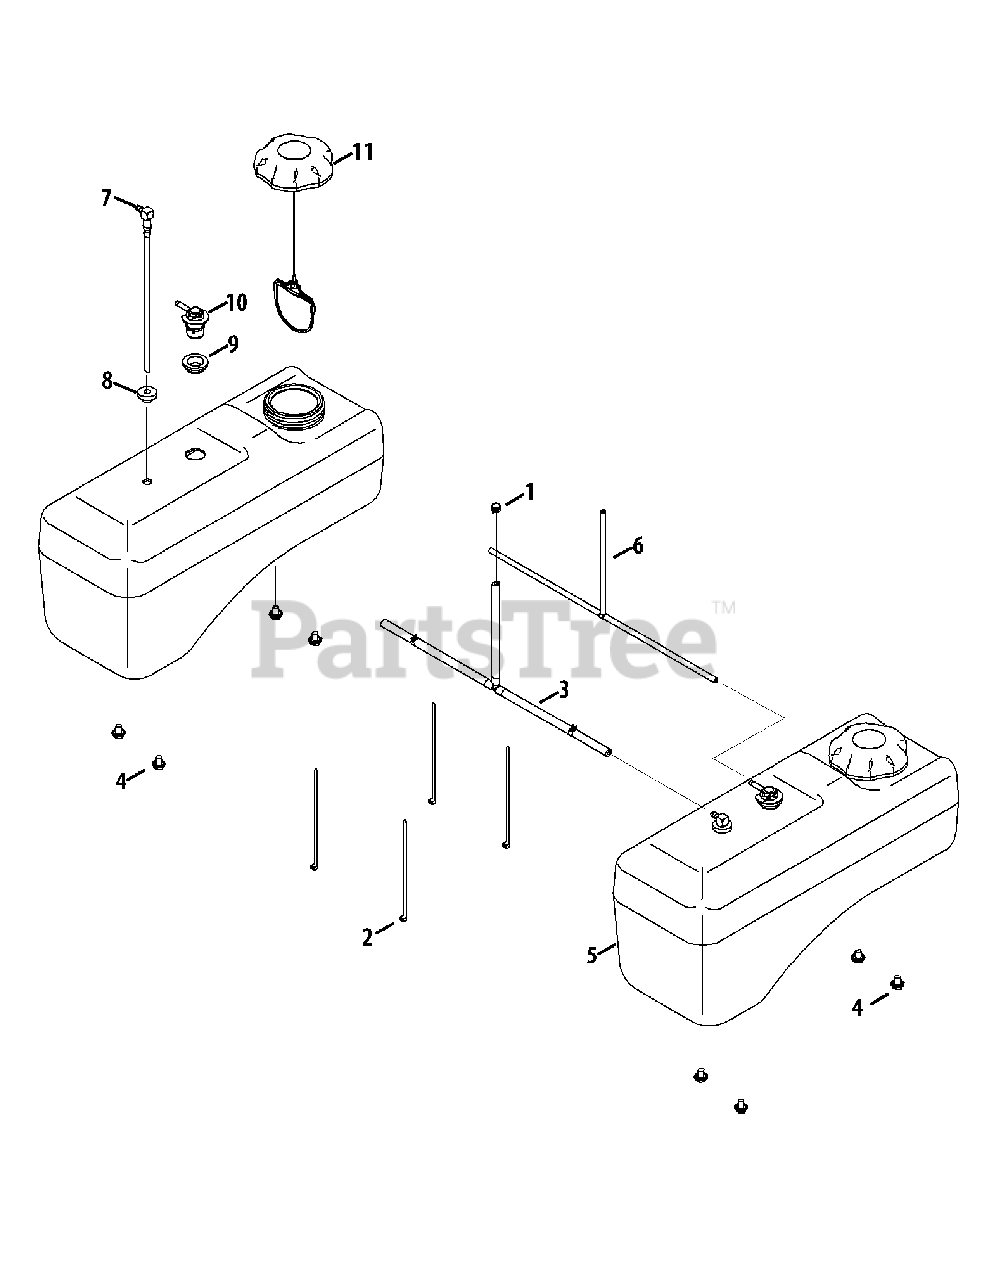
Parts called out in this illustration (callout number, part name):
1	Hose Clamp
2	Cable Tie
3	Hose Assembly
4	Hex Flange Screw, 3/8-16 x .500
5	Fuel Tank (7 gallon) (Inc. #7-11)
5	Fuel Tank (5 gallon) (Inc. #7-11)
6	Hose Assembly
7	Fuel Pick-up Fitting Valve
8	Fuel Tank Bushing
9	Rubber Grommet
10	Fuel Rollover Valve
